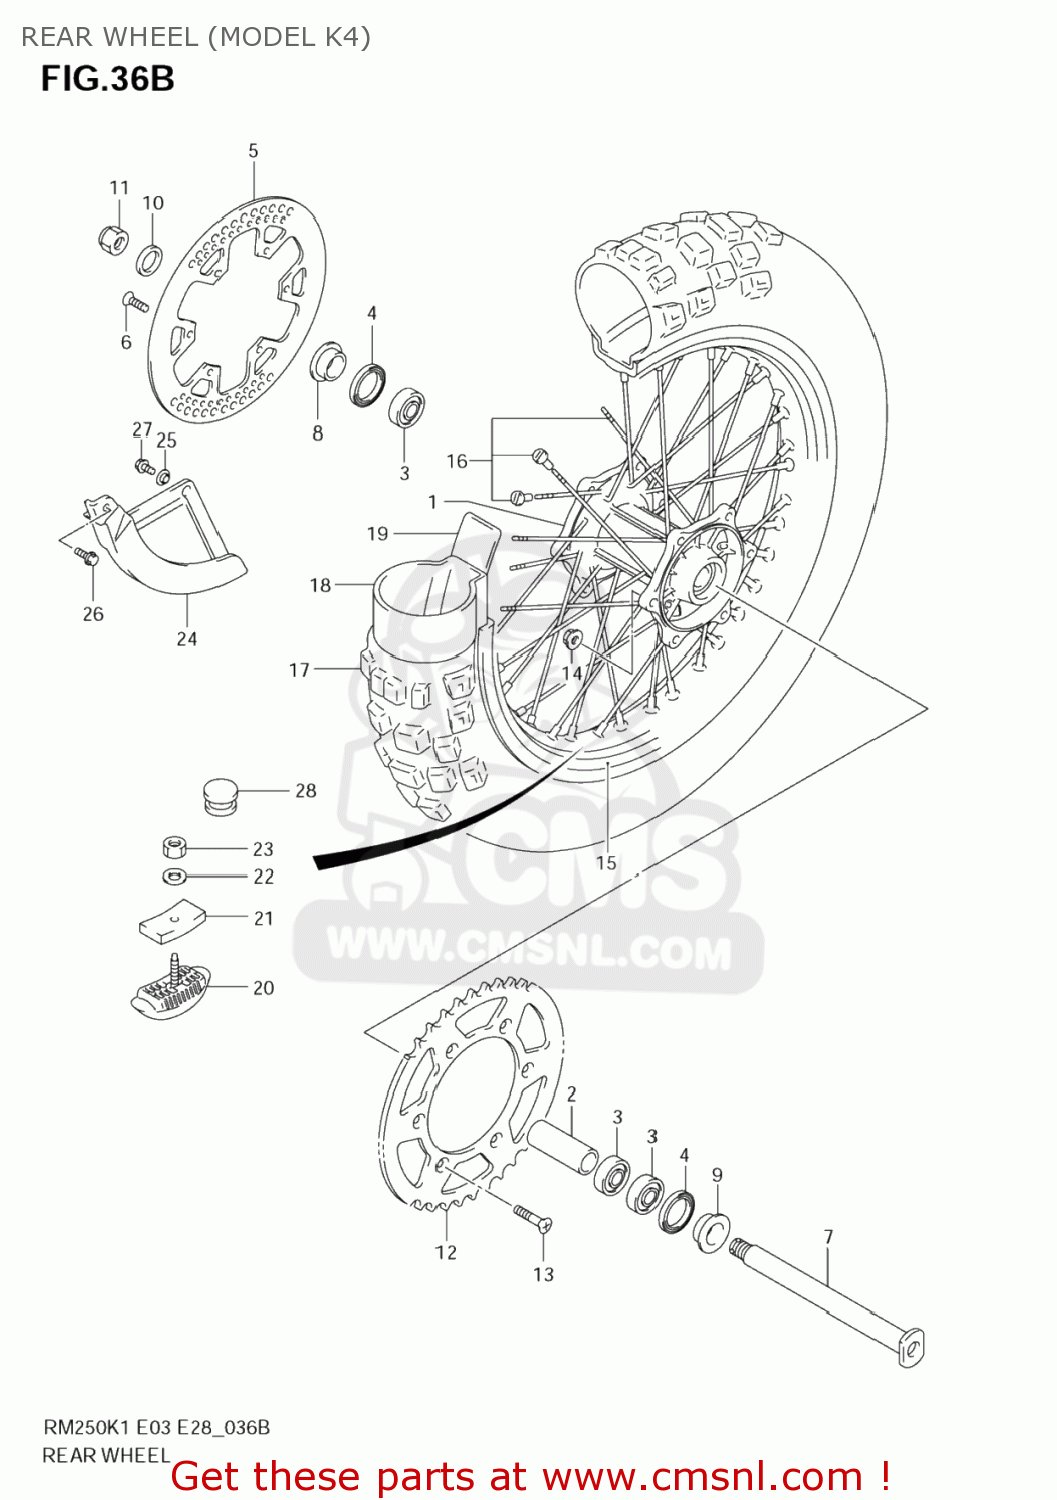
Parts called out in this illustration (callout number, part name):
1	HUB,RR WHEEL
2	SPACER,RR HUB BEARING
3	BEARING(22X44X12)
4	SEAL,OIL(30X44X7)
5	DISC,RR BRAKE
6	SCREW(6X18)
7	AXLE,RR
8	SPACER,RR AXLE
9	SPACER,RR AXLE
10	WASHER(19X32X3.2)
11	NUT
12	SPROCKET,RR(NT:50)
13	BOLT(8X28)
14	NUT
15	RIM,RR WHEEL(2.15X19 AL.)
16	SPOKE SET,RR WHEEL
17	TIRE,RR(110/90 19)
18	TUBE ASSY,WHEEL INNER
19	PROTECTOR,WHL INR TUBE
20	STOPPER,BEAD(2.15)
21	CUSHION,BEAD STOPPER
22	WASHER
23	NUT
24	COVER,RR DISC
25	WASHER,RR BRAK
26	BOLT
27	BOLT
28	CAP(OD:12)
